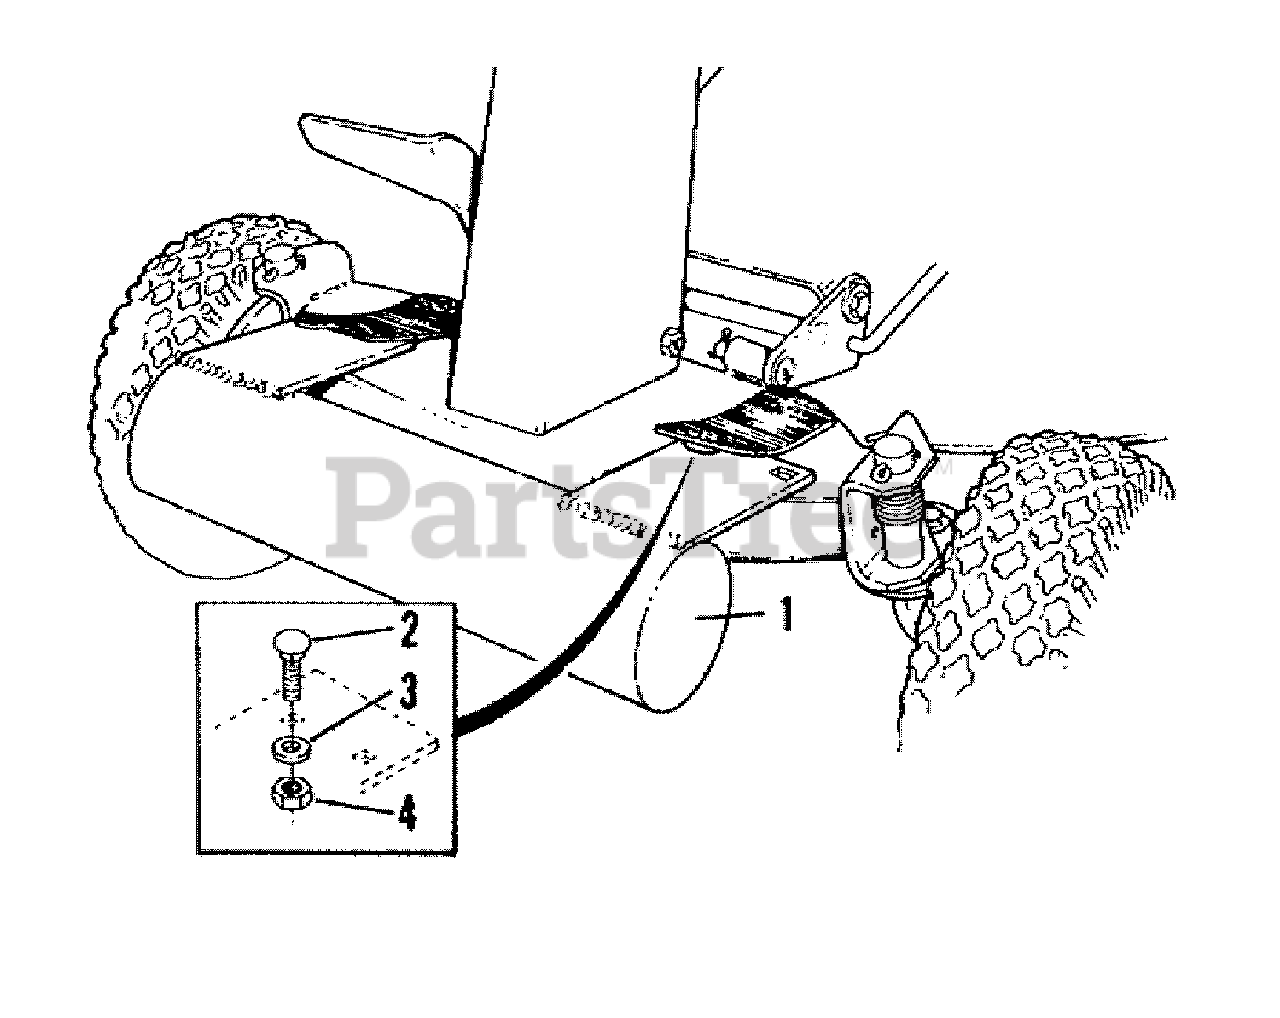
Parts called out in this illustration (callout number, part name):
1	COUNTERWEIGHT ASSEMBLY
2	BOLT, Carriage, 3/8-16 x 1
3	LOCKWASHER, 3/8
4	NUT, Full Hexagon, 3/8-16
